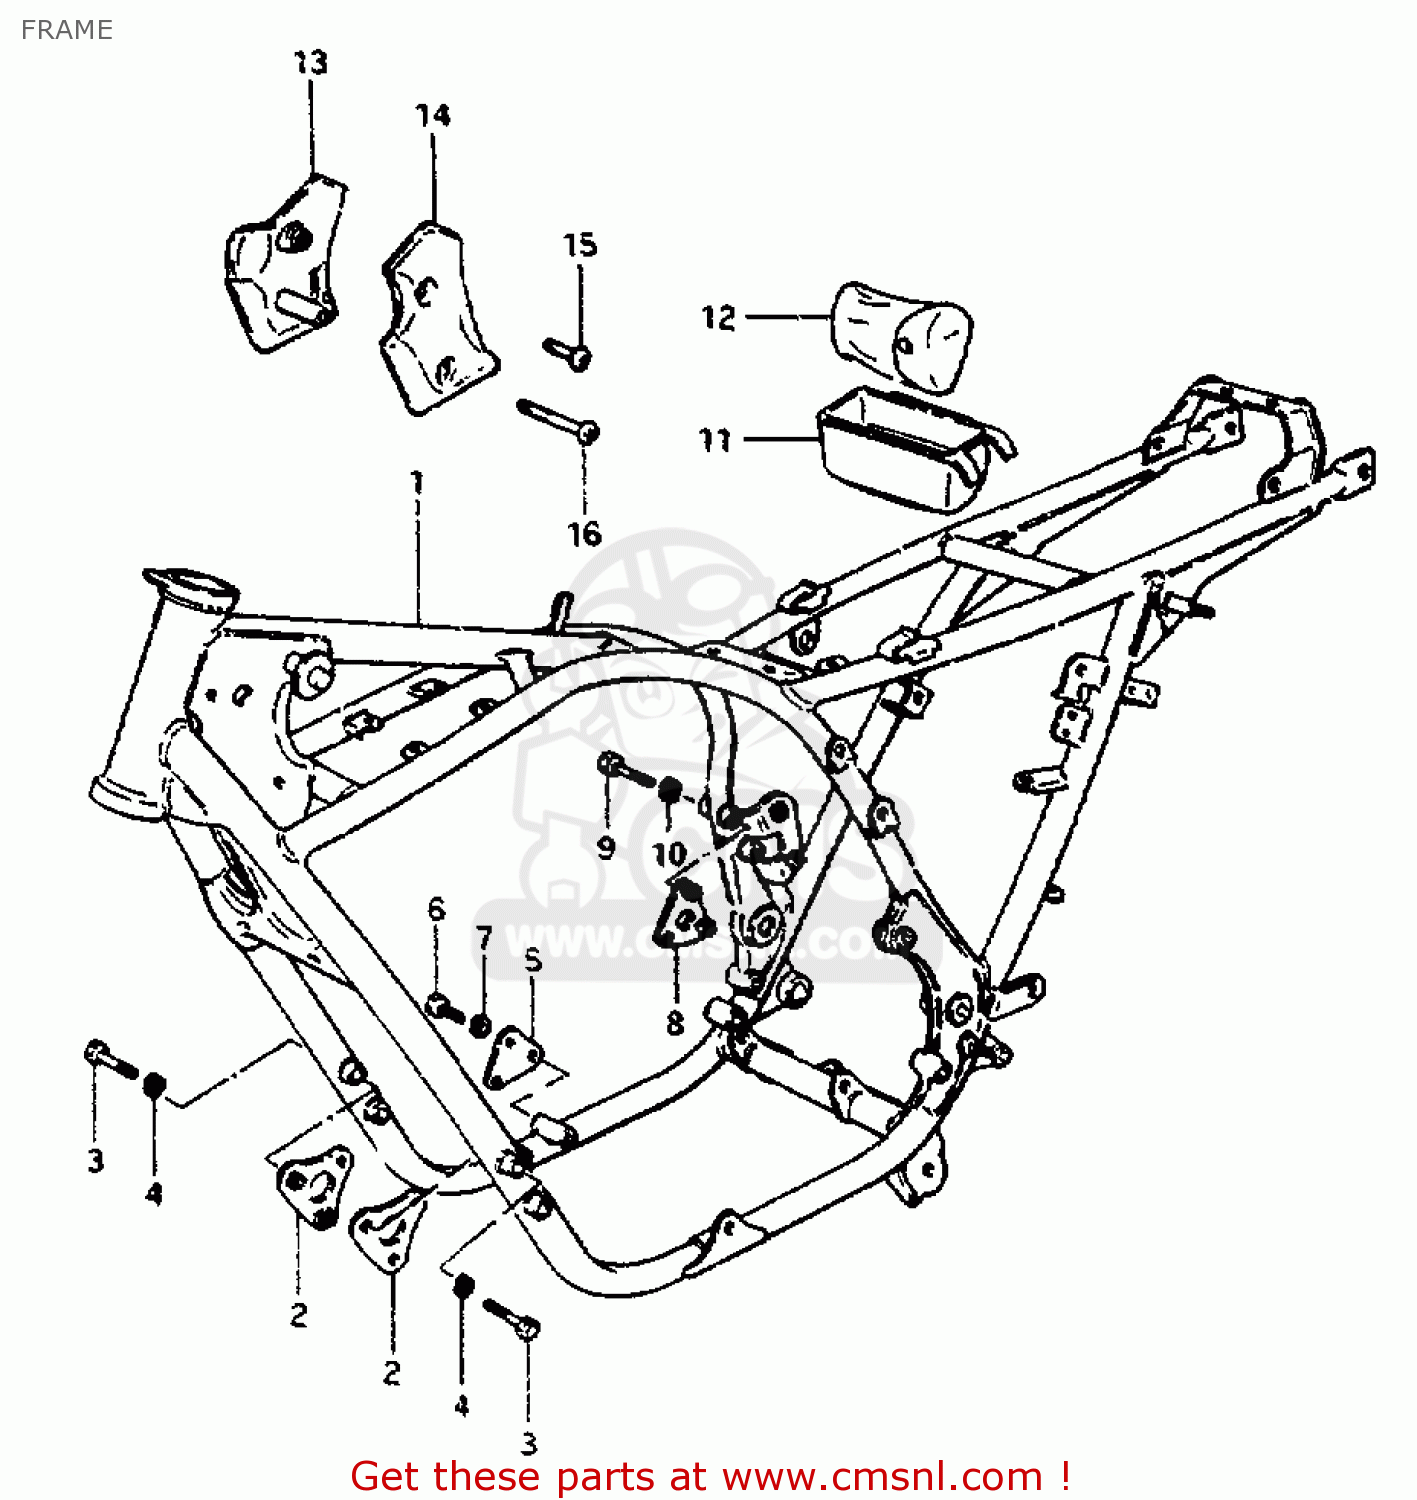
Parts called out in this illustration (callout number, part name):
1	FRAME
2	PLATE,ENGINE MOUNTING
3	BOLT
4	LOCK WASHER
5	PLATE,ENGINE MOUNTING
6	BOLT
7	LOCK WASHER
8	PLATE,ENGINE MOUNTING
9	BOLT 8X55
10	LOCK WASHER
11	HOLDER,TOOL
12	TOOL SET
13	COVER,FRAME HEAD,RIGHT
14	COVER,FRAME HEAD,LEFT
15	SCREW
16	SCREW
